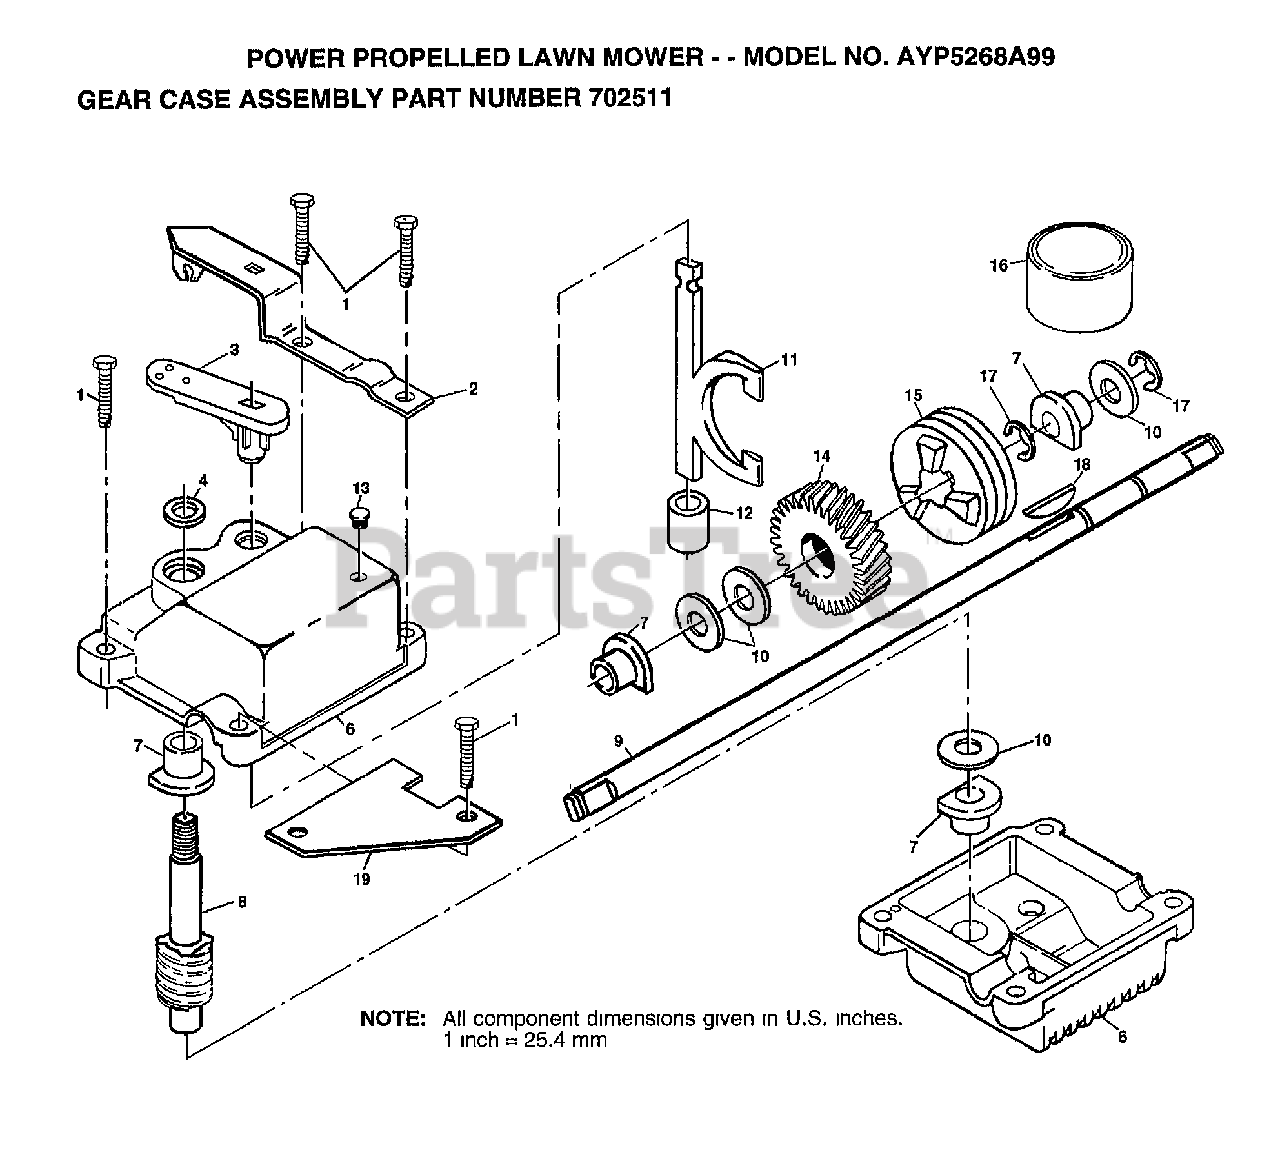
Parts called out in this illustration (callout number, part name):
1	SCREW.1/4-20
2	BRACKET.GEARCASE
3	SHIFTER
4	SEAL
6	KIT GEARCASE HALV
7	BEARING
8	SHAFT.WORM
9	SHAFT.DRIVE
10	THRUST WASHER
11	CLUTCH YOKE
12	BUSHING.GEAR BOX
13	PLUG PM
14	GEAR.HELICAL
15	CLUTCH JAW
17	RING T
18	HI PRO KEY
